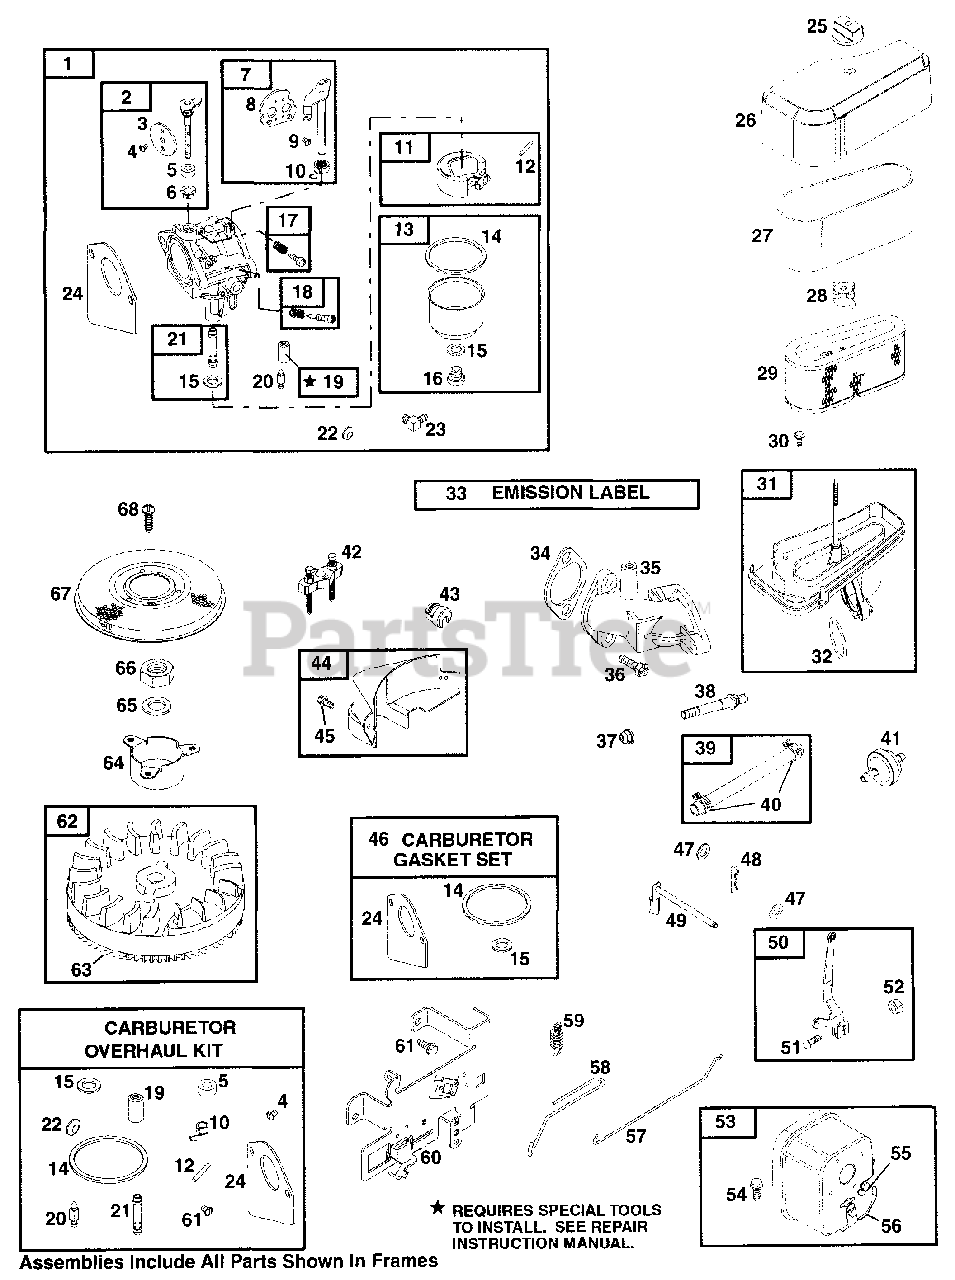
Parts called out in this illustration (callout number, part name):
1	Carburetor
2	Throttle Shaft Kit
3	Throttle Valve
4	Screw (Throttle Valve)
5	Seal-Throttle Shaft
6	Bushing-Throttle Shaft
7	Choke Shaft Kit
8	Valve-Choke
9	Screw (Choke Valve)
10	Spring & Seal Assembly
11	Float-Carburetor
12	Pin-Float Hinge
13	Bowl-Float
14	Gasket-Float Bowl
15	Sealing Washer
16	Screw (Float Bowl)
17	Kit-Idle Speed
18	Kit-Idle Mixture
19	Inlet Seat
20	Float Needle Valve
21	Nozzle-Carburetor
22	Plug-Welch
23	Connector-Hose
24	Intake Gasket
25	Knob-Air Cleaner
26	Cover-Air Cleaner
27	Filter-Pre Cleaner
28	Seal-Air Cleaner Stud
29	Filter-A/C Cartridge
30	Screw (Air Cleaner Base Mounting)
31	Base-Air Cleaner
32	O-Ring Seal (Air Cleaner Base)
33	Label-Emissions
34	Intake Gasket
35	Intake Manifold
36	Screw (Intake Manifold)
37	Nut (Carburetor)
38	Stud (Carburetor)
39	Line-Fuel
40	Clamp-Hose
41	Filter-Fuel
42	Flywheel Puller
44	Cover-Starter Drive
45	Screw (Starter Drive Cover)
46	Carburetor Gasket Set
47	Washer (Governor Crank)
48	Pin-Cotter
49	Crank-Governor
50	Governor Control Lever
51	Bolt (Governor Control Lever)
52	Nut (Governor Control Lever)
53	Muffler-Exhaust
54	Screw (Muffler Bracket)
55	Screw (Muffler-Exhaust)
56	Shield-Heat
57	Mechanical Governor Link
58	Choke Link
59	Governor Spring
60	Bracket-Control
61	Screw (Control Bracket)
63	Gear-Ring
64	Cup-Flywheel
65	Washer (Flywheel)
66	Nut (Flywheel)
67	Rotating Screen
68	Screw (Rotating Screen)
